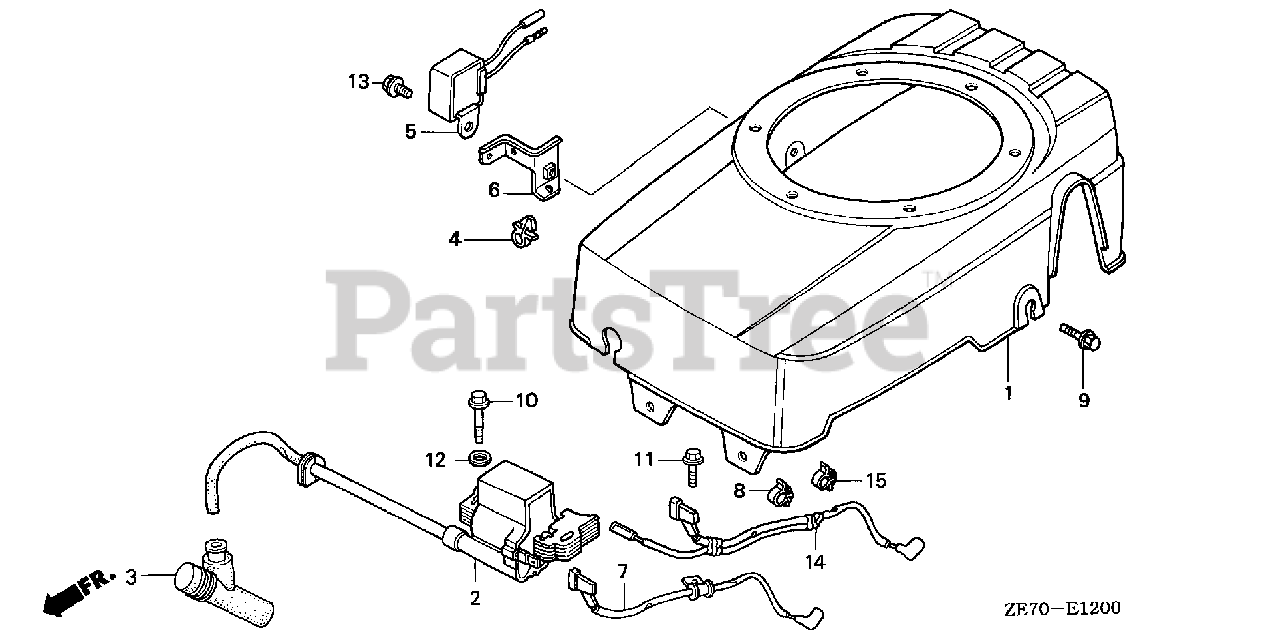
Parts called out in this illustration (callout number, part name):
1	COVER, FAN *R8* (BRIGHT RED)
2	COIL ASSY., IGNITION
3	CAP ASSY., NOISE SUPPRESSOR
7	WIRE, STOP SWITCH
8	HOLDER, STOP SWITCH WIRE
9	BOLT, FLANGE (6X14) (CT200)
10	BOLT, FLANGE (6X25) (CT200)
11	BOLT, FLANGE (5X10)
15	CLAMP, BRAKE PIPE (GRAY)
